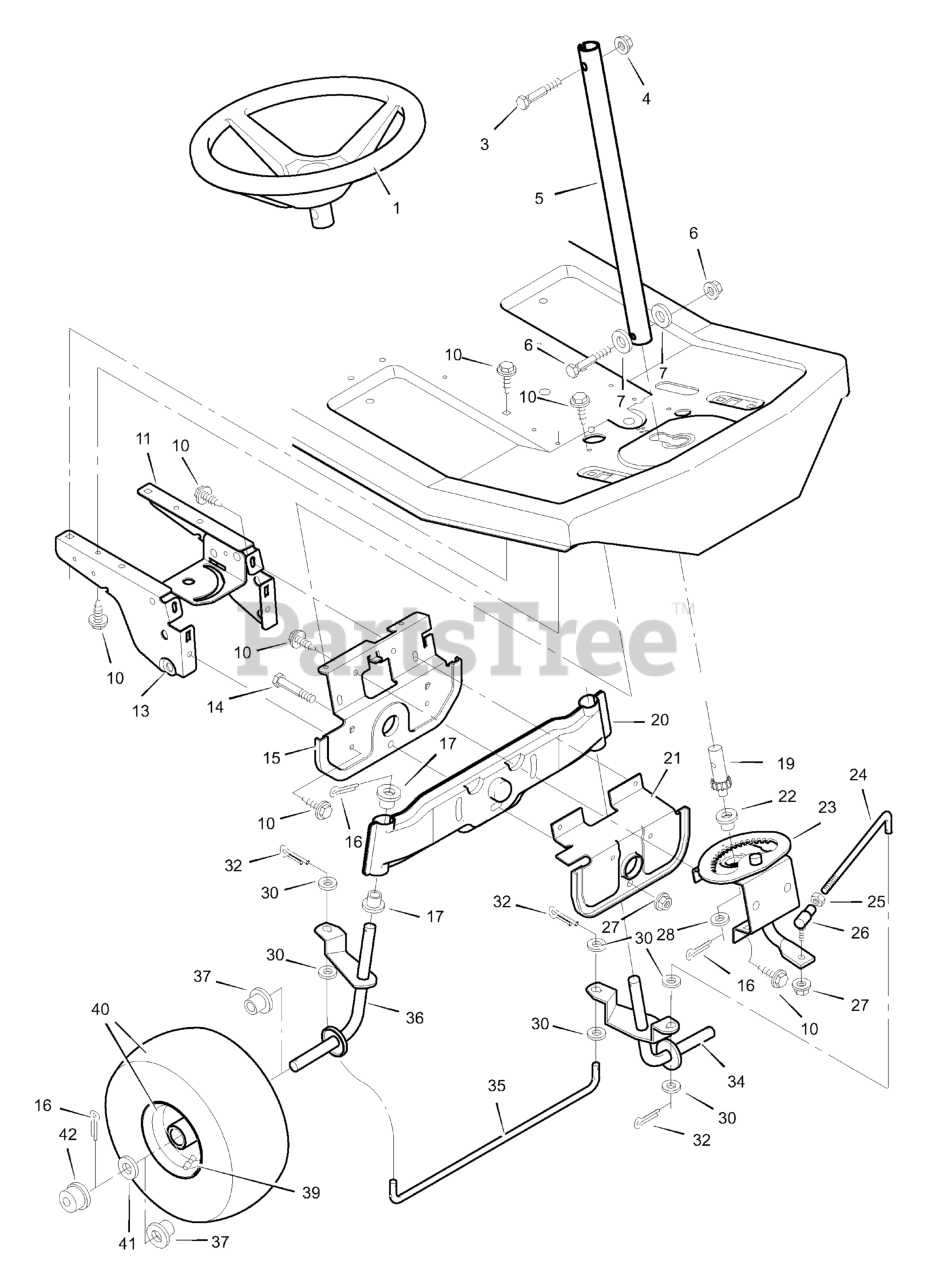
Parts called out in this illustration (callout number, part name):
1	Steering Wheel
3	Bolt, Hex
4	Locknut, Flange
5	Post, Steering
6	Nut, Hex
7	Washer
11	Plate, Left Suspension
13	Plate, Right Suspension
14	Bolt, Hex
15	Support, Front Axle
16	Pin, Cotter
17	Bearing, Spindle
19	Gear, Pinion
20	Axle Assembly, Front
21	Hanger Assembly, Front Axle
22	Bearing
23	Sector Assembly
24	Rod, Drag Link
25	Nut, Hex
26	Ball Joint, Steering
27	Locknut, Flange
32	Pin, Cotter
34	Spindle Assembly, Left
35	Rod, Tie
36	Spindle Assembly, Right
37	Bearing, Wheel
39	Valve Stem
40	Wheel & Tire Assembly
42	Cap, Hub
